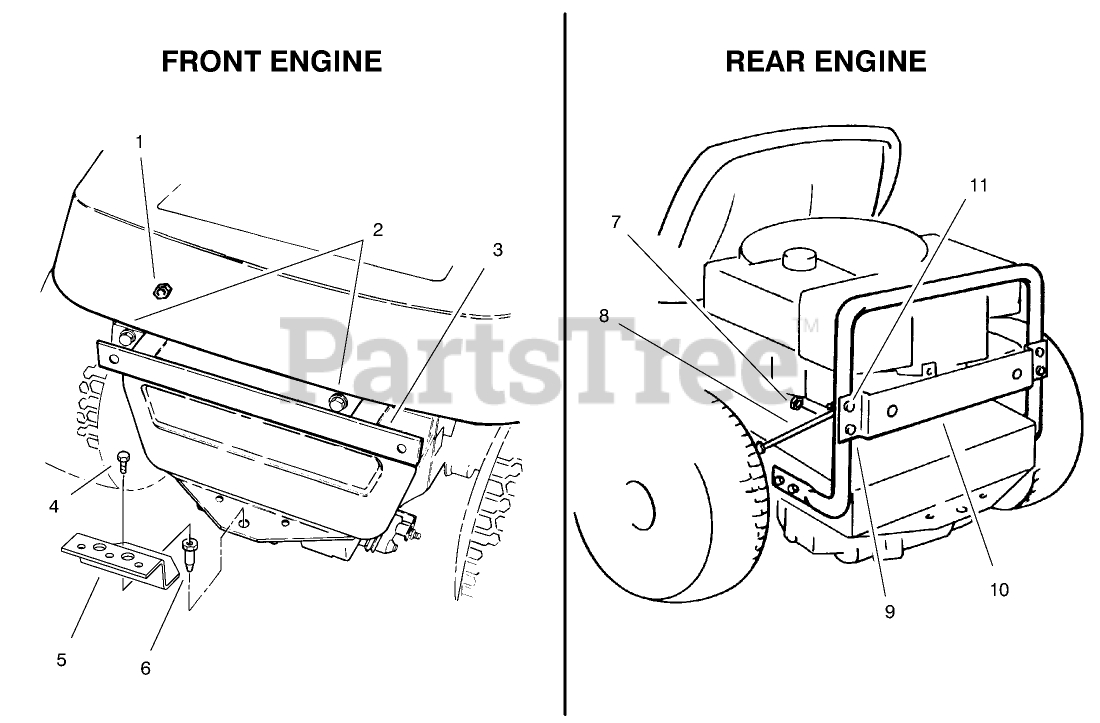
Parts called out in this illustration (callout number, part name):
1	NUT-LOCK, NI
2	SCREW-HH
3	BRACKET-CHANNEL
4	SCREW-HH
5	BRACKET-MOUNTING, BAG
6	PIN-MOUNTING, LOWER
7	NUT-LOCK, NI
8	BAGGING KIT BRACE
9	SCREW-HH
10	BAGGING KIT PLATE
11	SCREW-HH
